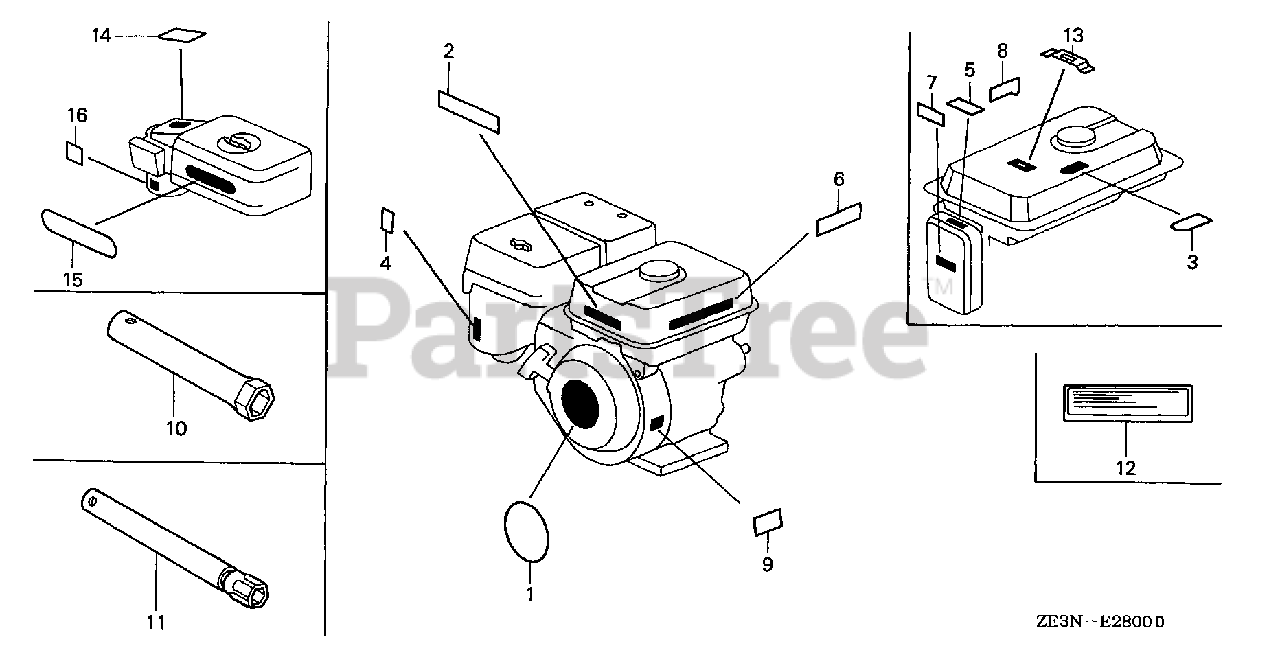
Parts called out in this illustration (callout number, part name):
1	EMBLEM
2	LABEL, CAUTION
4	MARK, CHOKE (EXTERNAL)
6	MARK, OIL ALERT (E)
11	WRENCH, SPARK PLUG
